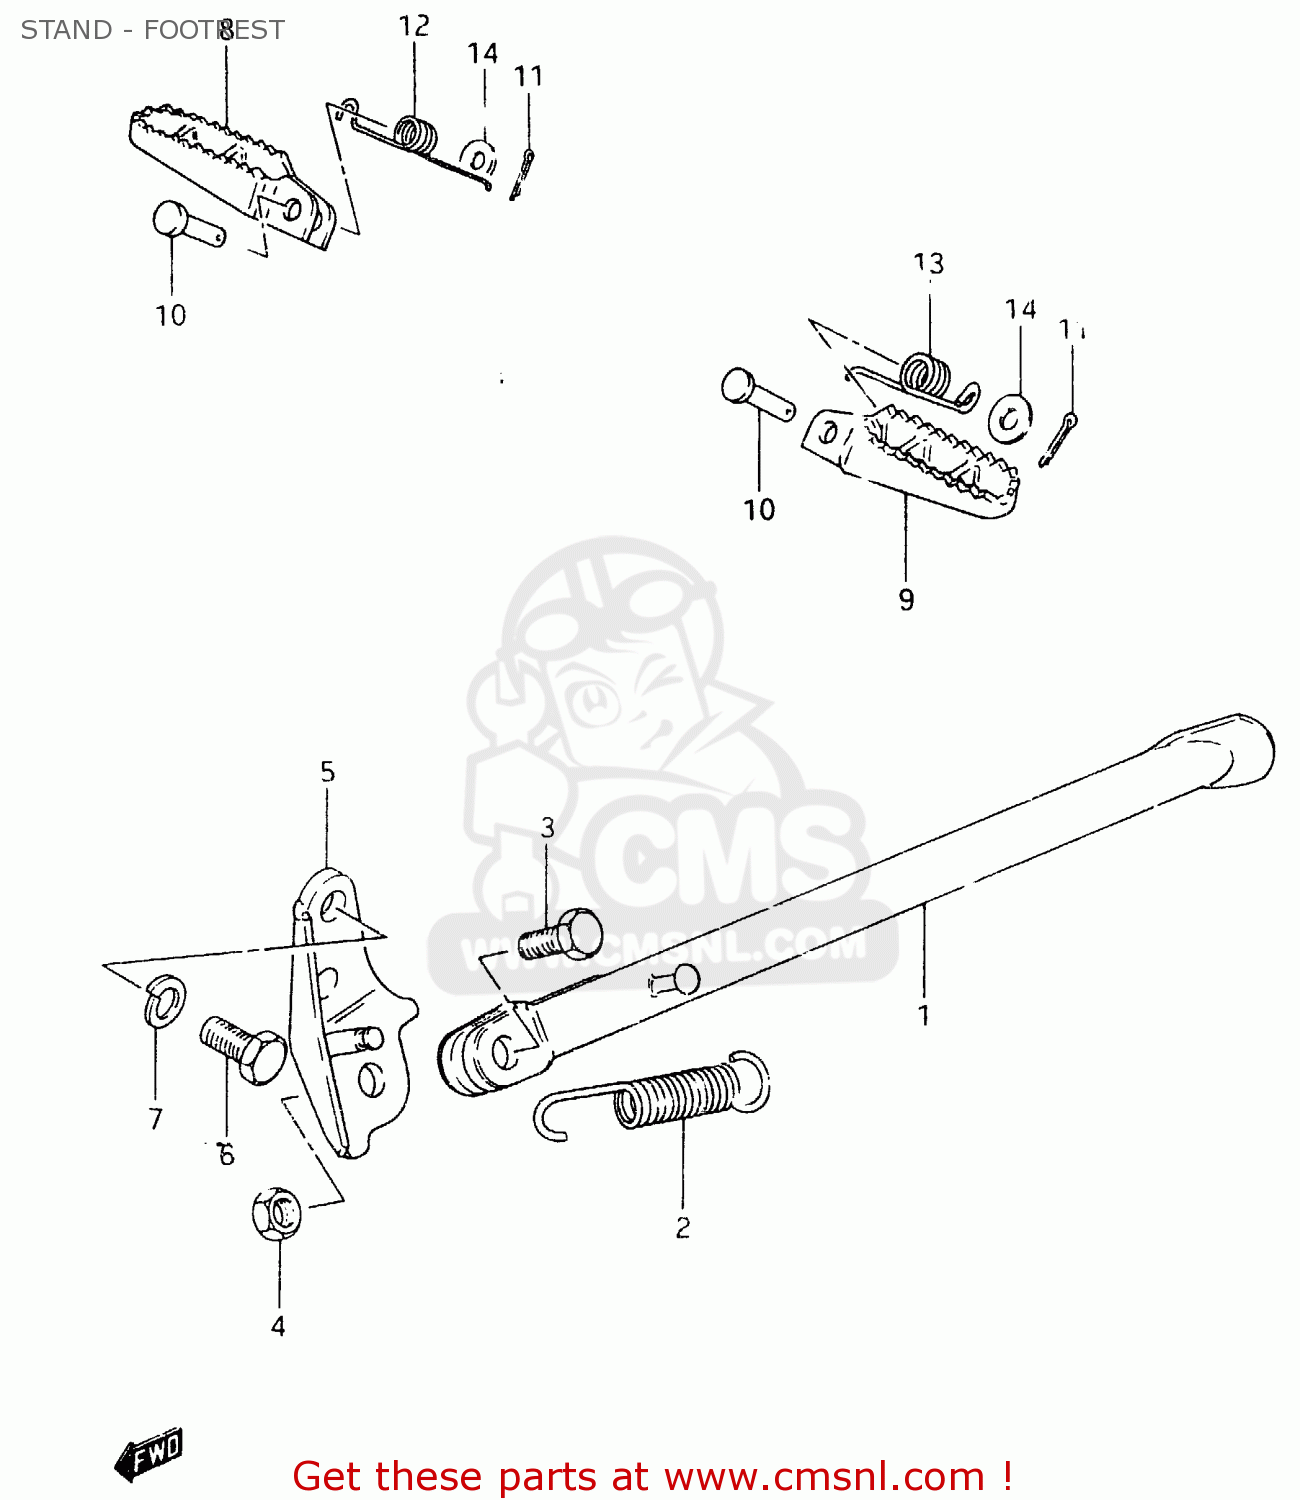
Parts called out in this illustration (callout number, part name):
1	STAND,SIDE
2	SPRING
3	BOLT(10X30)
4	NUT
5	BRACKET,SIDE STAND
6	BOLT(10X19)
7	LOCK WASHER
8	RUBBER,FOOTREST
9	FOOTREST
10	PIN
11	PIN 20X20
12	SPRING
13	SPRING
14	WASHER
